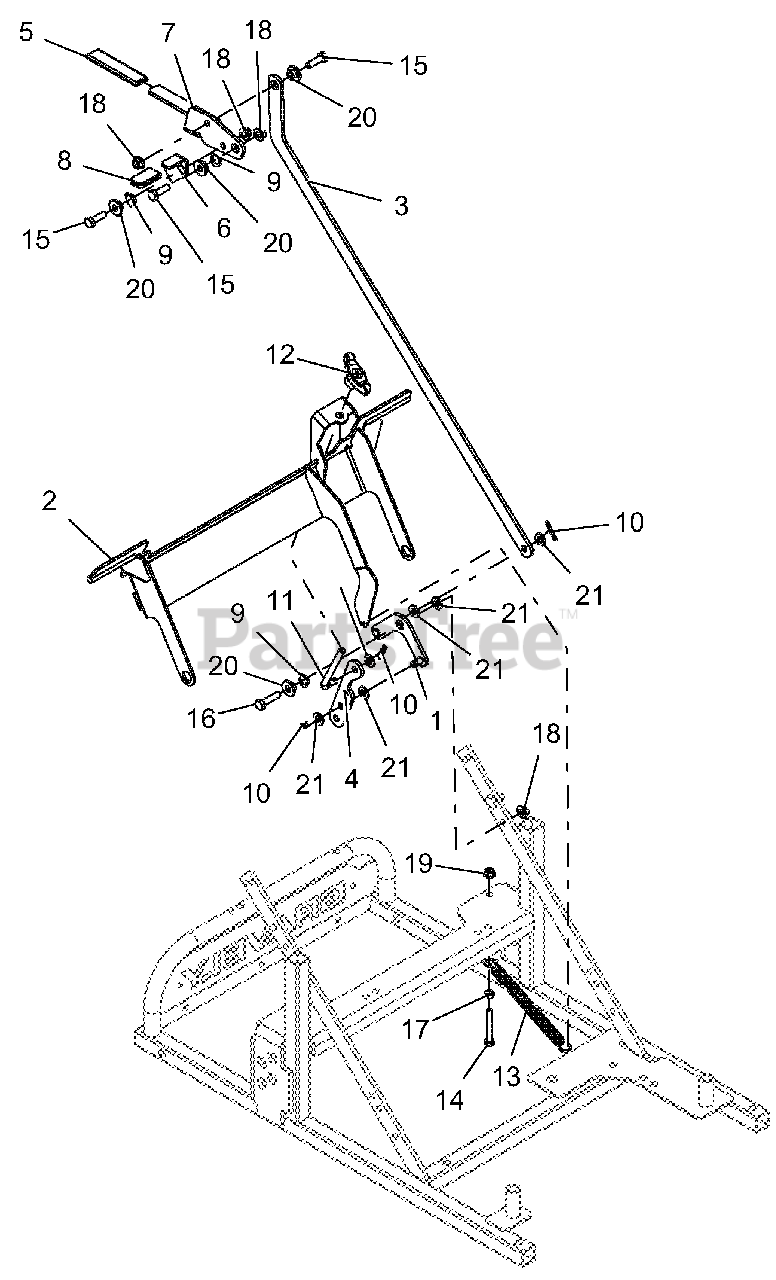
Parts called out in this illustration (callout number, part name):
1	WLDMT, BELL CRANK, HWM BRAKE (BLACK)
2	WLDMT, HWM BRAKE FRAME (BLACK)
3	BAR, ENGAGEMENT LEVER CONN. (BLACK)
4	BRKT, ENGAGE, ADJ (BLACK)
5	GRIP, MZR/MOMENT SP 7/8X3/4X4
6	LOCK, HWM PARK BRAKE (BLACK)
7	LEVER, SP ENGAGEMENT (BLACK)
8	GRIP, THUMB LATCH
9	WSHR, WAVE .50X.75X.015 .13FRHT
10	PIN-HAIR, ENDRIES #25 YWZC
11	THDED ROD .31-18X3.0THD YZ
12	KNOB, WING .31-18 UNC NYL/TALC
13	SPRG, EXTENSION
14	BLT-HEX .25-20X2.00 GR5 YWZC
15	BLT-HEX .31-18X1.00 GR5 YWZC
16	BLT-HEX .31-18X1.25 GR5 YWZC
17	NUT-HEX .25-20 YWZC
18	NUT, LK-TOP-FLG .312-18 YWZC
19	NUT, LK-TOP-FLG .25-20 YWZC
20	BSHG, FLG .32X.500.344X.880
21	WSHR-FL-STL.344X.688X.065YWZC
